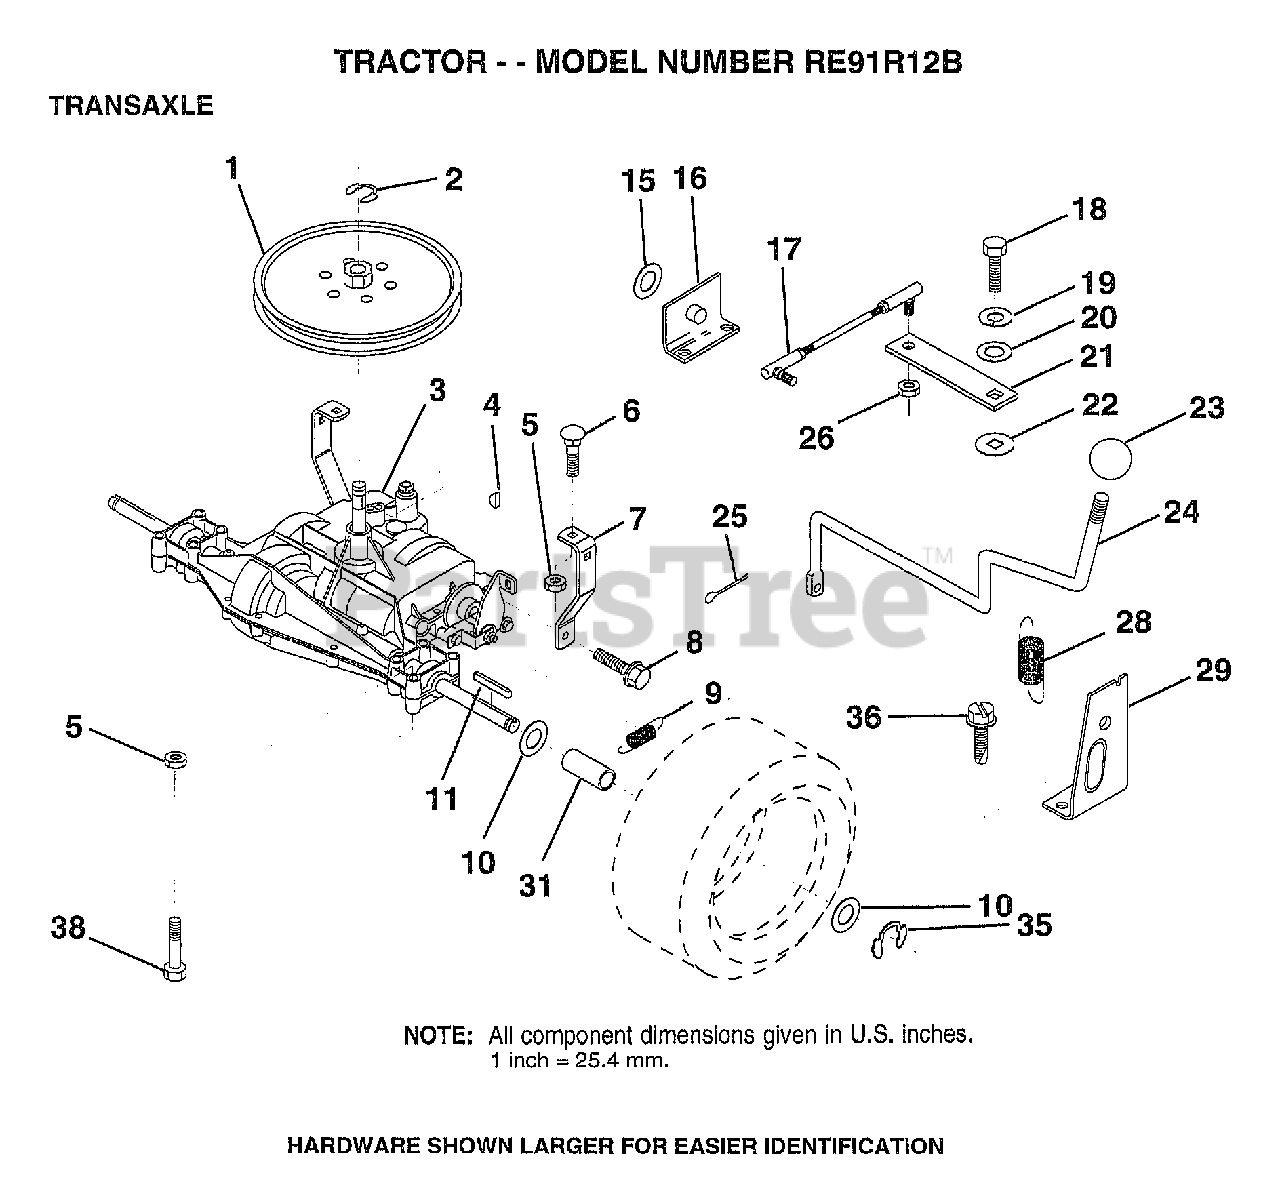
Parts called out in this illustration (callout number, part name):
1	PULLEY
6	BOLT
7	"STRAP,TORQUE"
8	SCREW
9	SPRING.BRAKE.RETU
10	WASHER
11	SQUARE KEY
16	"SUPT,HDLE SHT LH"
17	LINK SHIFT
18	BOLT.1/4-28.W/PAT
19	LOCKWASHER
20	WASHER LT
22	WASH-SHFT PLT LT
23	KNOB T (1/2-HOLE)
24	"ROD,SHIFT"
25	PIN COTTER 1/8
26	NUT.LOCK.5/16-24
28	"SPRING,EXT"
29	"SUPT,HDLE RH"
31	SPACER AXLE
32	WASHER
35	E-RING LT
36	SCREW
38	BOLT.HX.FLG.5/16
